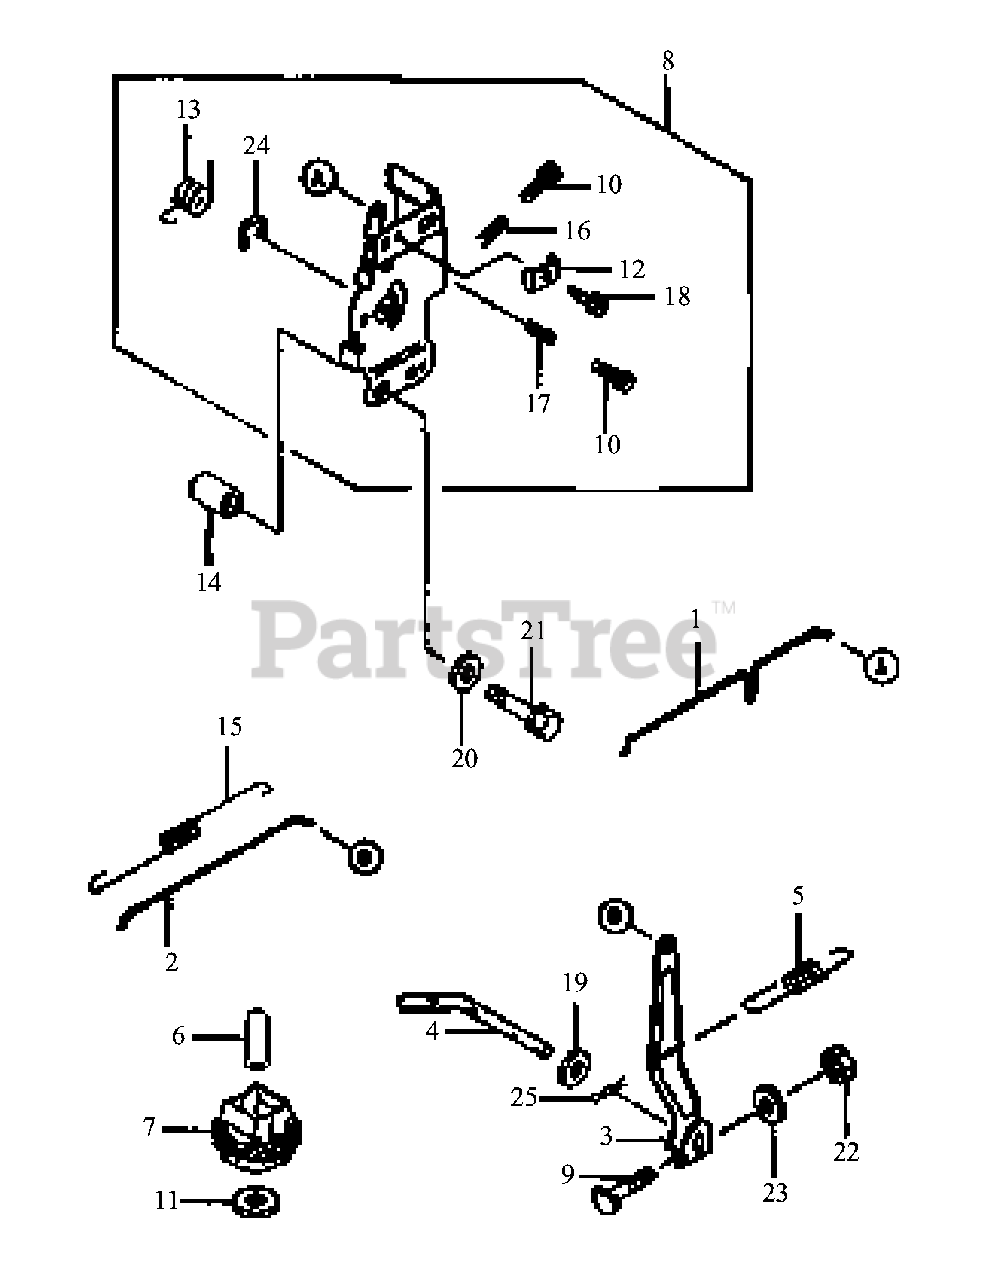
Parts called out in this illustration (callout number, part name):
2	Link, Governor
3	Arm, Assembly
5	Spring, Governor
8	Panel, Control
10	Screw
16	Spring
19	Washer, 6.5x11.5x2.0
23	Washer, Plain
24	Circlip, Type E
